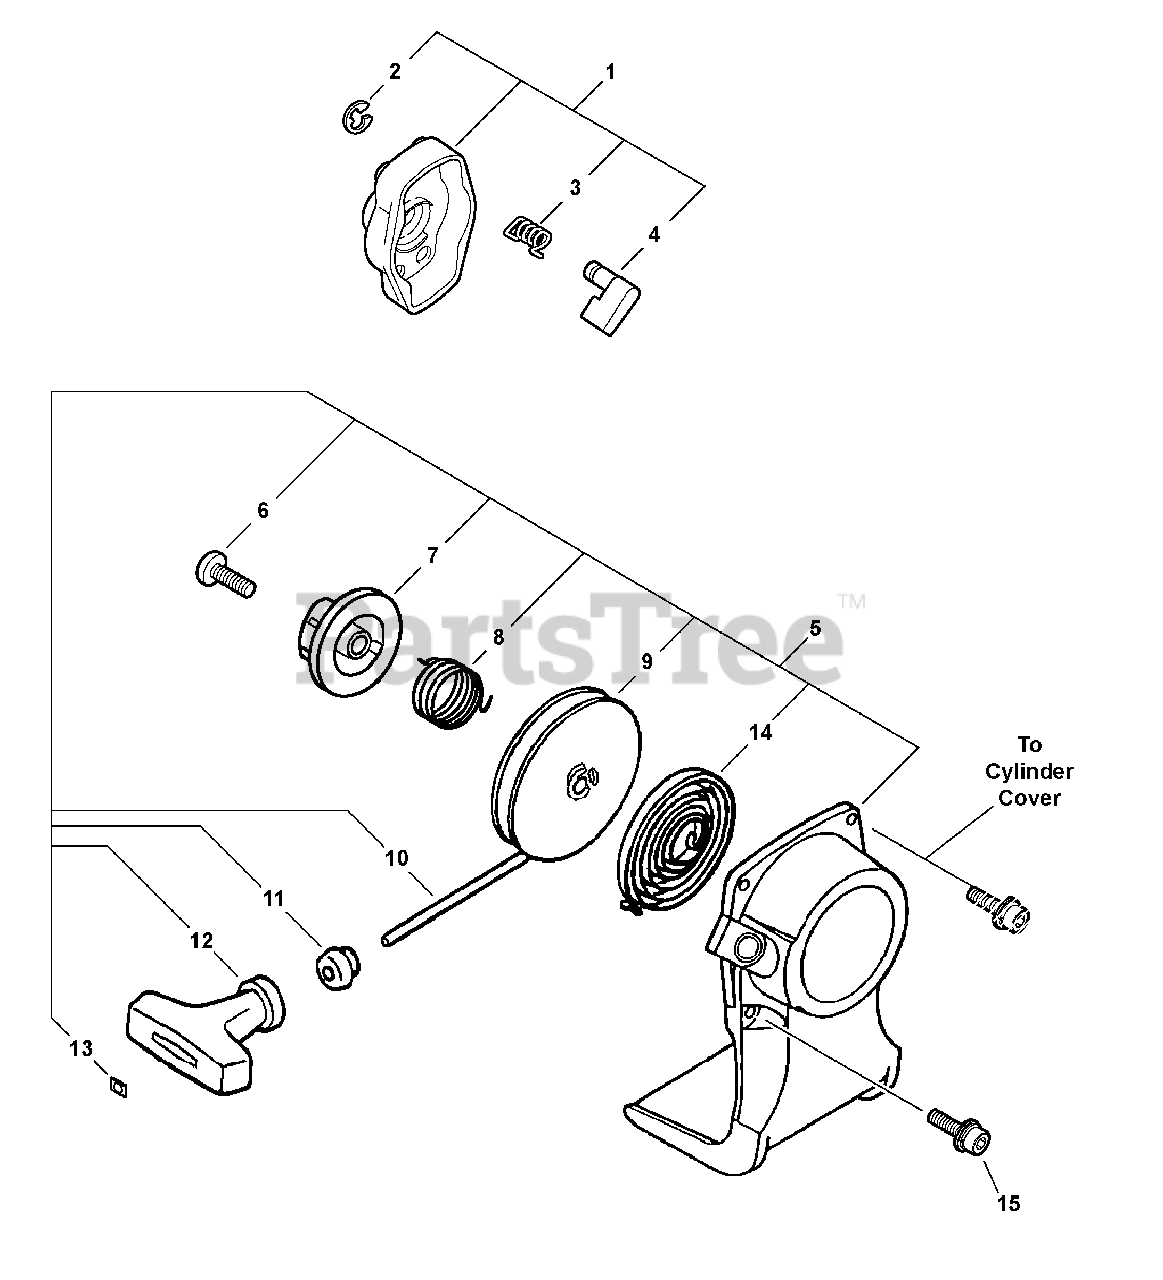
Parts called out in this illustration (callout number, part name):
1	Starter Pawl Asy
3	Spring, Pawl Return
4	Pawl, Starter
5	Starter Asy
6	Screw
7	Plate, Cam
8	Spring, Damper
9	Drum
10	Rope, Starter - 3x700mm
11	Guide, Rope
12	Grip, Starter
13	Clip, Starter Rope
14	Spring, Rewind
15	Screw 4x16
